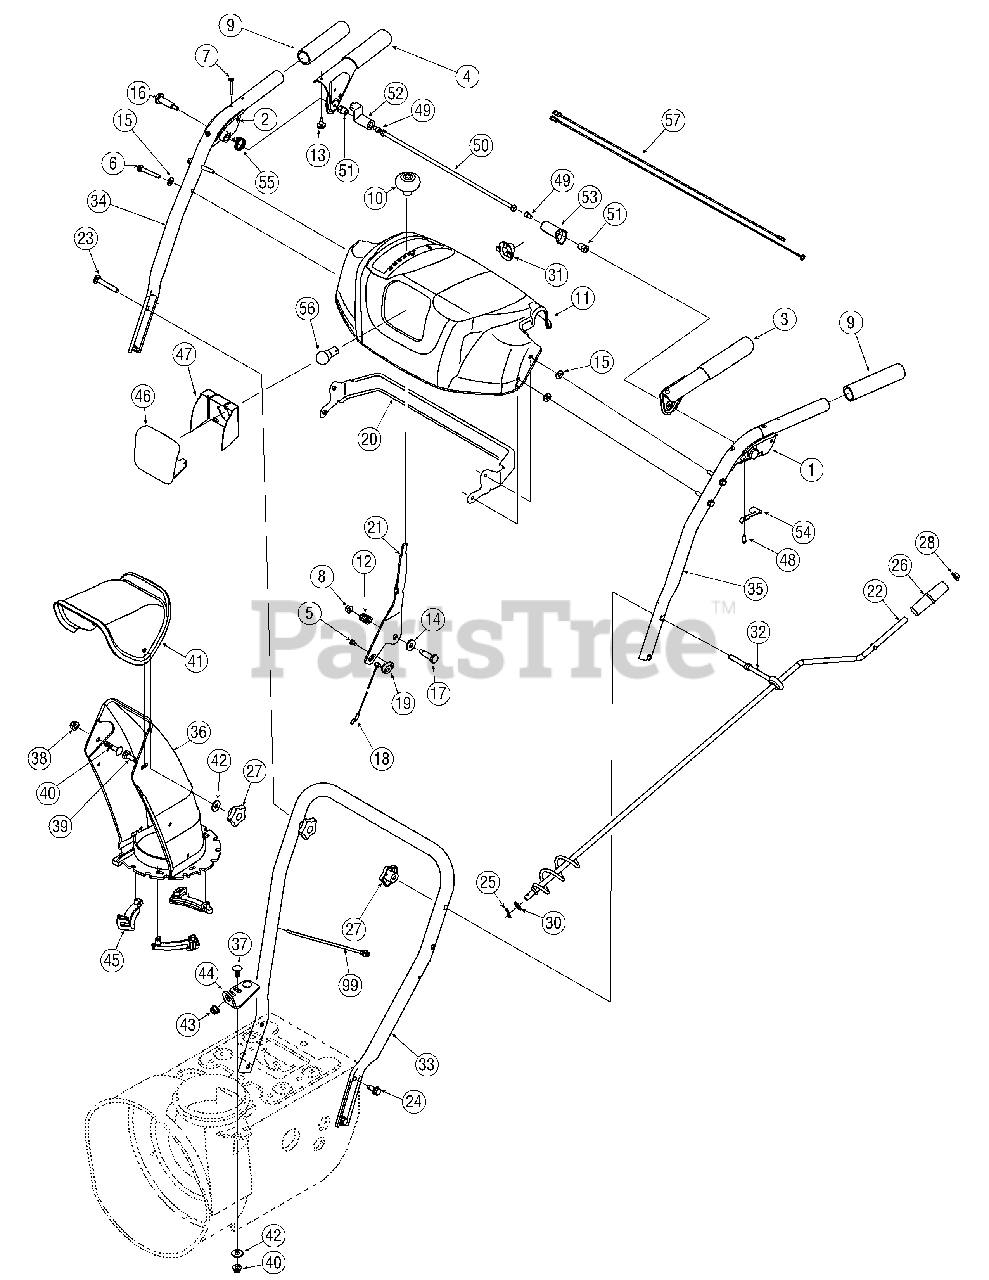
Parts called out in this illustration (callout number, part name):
1	Handle Assembly, Lock, LH
2	Handle Assembly, Lock, RH
3	Handle Ass’ y, Engagement LH
4	Handle Ass’y, Engagement, RH
5	Screw, #10-16, 0.500
6	Screw, 1/4-20, 1.750
7	Screw, Machine, #10-24, 1.375
8	Nut, Flange Lock, 1/4-20, Nylon
9	Grip, 1.0 ID x 5.0
10	Knob, Shift
11	Handle Panel, H-Style
12	Spring, .39 x .60 x .88
13	Bumper, Rubber, .62 OD x .22
14	Washer, Flat, .385 x .870 x .092
15	Washer, Flat, .25 x .630 x .0515
16	Screw, Shoulder, .43 x 1.34, 1/4-20
17	Screw, Shoulder, .374 Dia. x 1.05
18	Cable, Speed Selector
19	Barrel Holder, Cable, LH
20	Bracket, Panel
21	Lever, Shift
22	Crank Assembly, Chute
23	Screw, Carriage, 5/16-18, 2.25
24	Screw, 5/16-18, 0.75, Gr5
25	Pin, Cotter, .072 x 1.13
26	Crank Knob, 1.0 Dia. x 3.2, Black
27	Knob Assembly, Wing Nut, 5/16-18
28	Cap, Push, 3/8 Rod
29	Grommet, .44 ID x .94 OD x .50
30	Washer, Flat, .375 x .738 x .063
31	Light Socket
32	Eye Bolt, Chute Crank
36	Chute, Lower, 5.0 Diameter
37	Bolt, Carriage, 5/16-18, 1.0
38	Nut, Flange Lock, 5/16-18, Nylon
39	Bolt, Carriage, 5/16-18, 1.0
40	Bolt, Carriage, 5/16-18, .750
41	Chute, Upper, w/ Label
42	Washer.349 ID x .879 OD x .063
43	Bushing, Plastic, .380
44	Bracket, Chute Crank
45	Flange Keeper, Chute
47	Reflector Label, Lens
48	Screw, #8-16 x 0.50
49	Screw, 1/4-20 x.375
50	Pivot Rod
51	Shoulder Nut, 1/4-20
52	Lock Plate
53	Clutch Lock Cam
54	Clutch Lock Spring
55	Torsion Spring
57	Wire Harness
